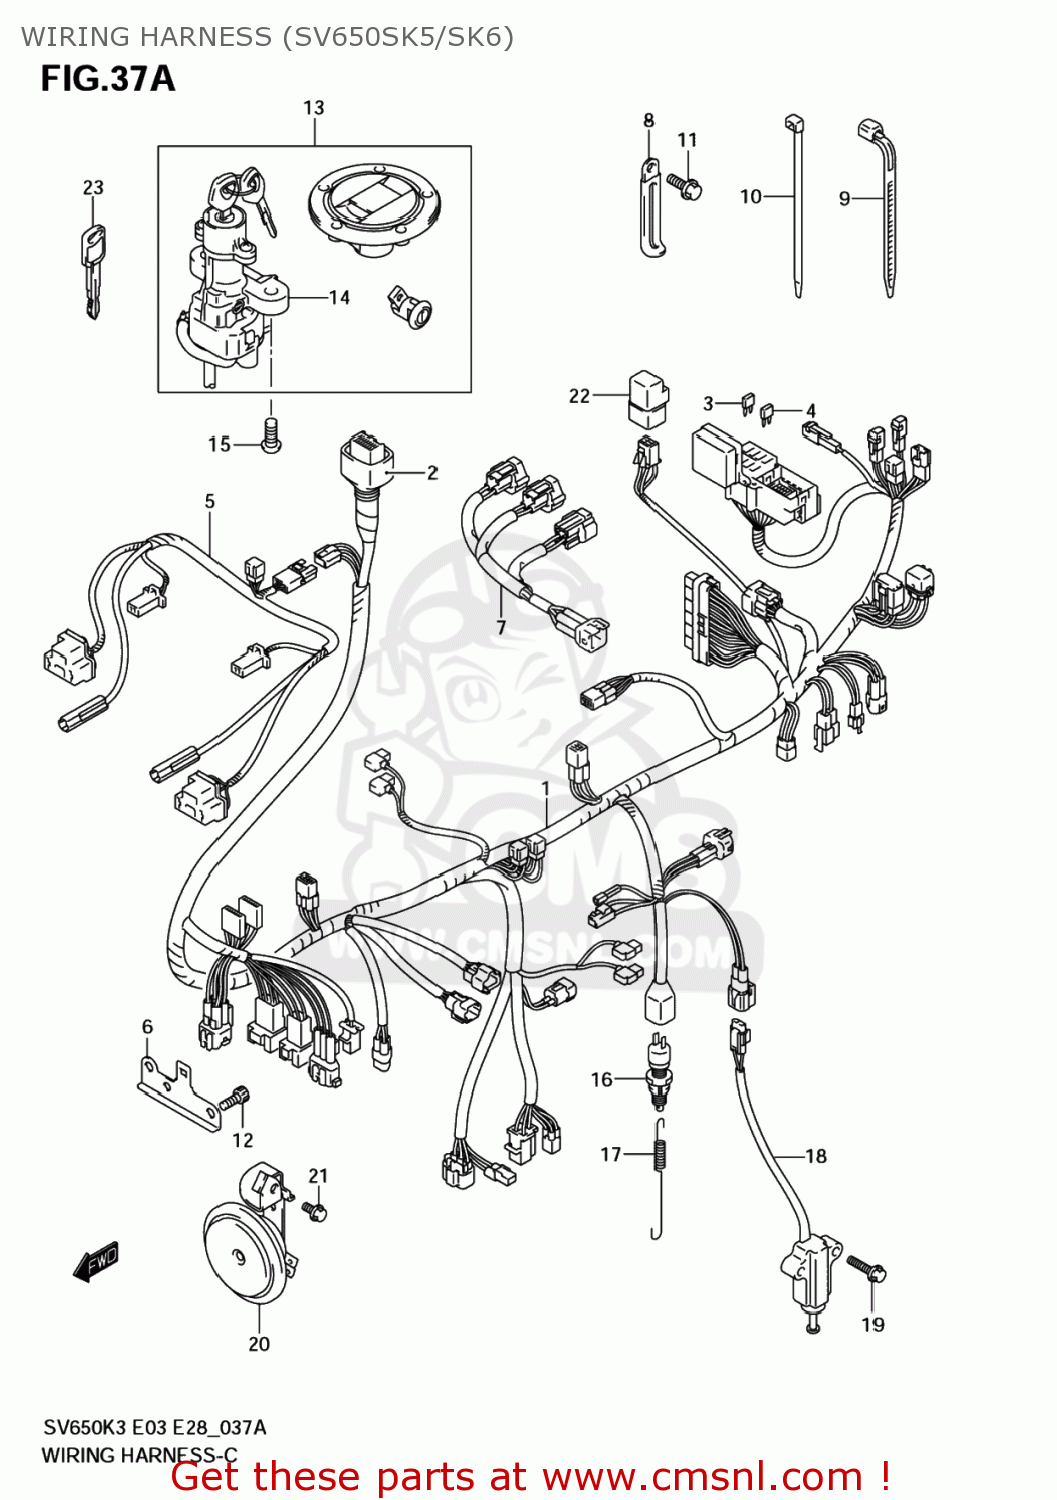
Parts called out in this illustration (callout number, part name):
1	HARNESS, WIRING, NO.1
2	COVER,SPEEDOMETER COUPLER
3	FUSE(10A)
4	FUSE(15A)
5	HARNESS,WIRING NO.2
6	HOLDER,COUPLER
7	WIRE,INJECTOR LEAD
8	CLAMP(L:45)
9	CLAMP(L:95)
10	CLAMP(L:145)
11	BOLT
12	BOLT,VAC.PIPE
13	LOCK SET
14	LOCK ASSY,STEERING
15	BOLT(8X20)
16	SWITCH ASSY,STOP LAMP
17	SPRING
18	SWITCH ASSY,SIDE STAND
19	BOLT
20	HORN ASSY
21	BOLT
22	RELAY ASSY
23	KEY,BLANK
